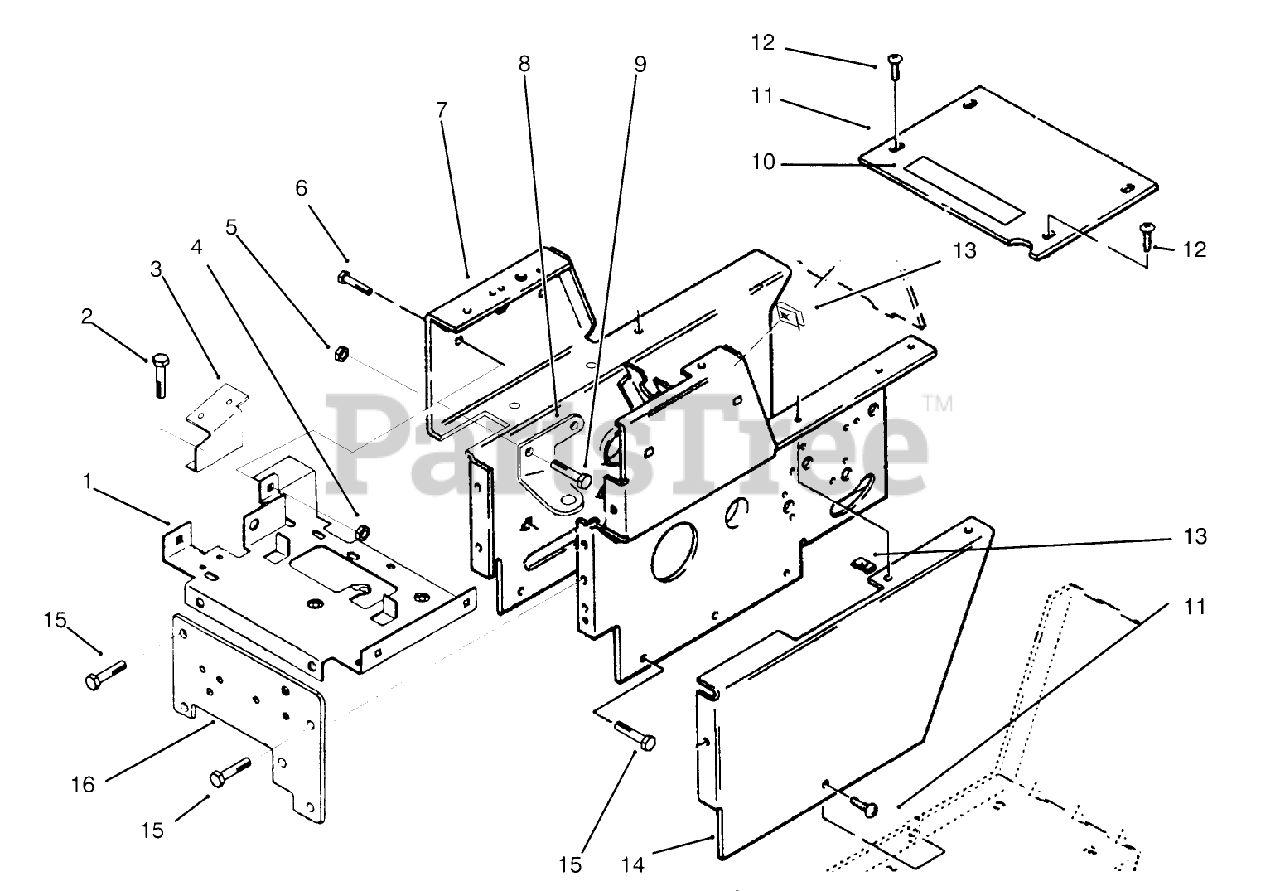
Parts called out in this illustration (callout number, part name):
2	Bolt
5	NUT-LOCK, NI
9	SCREW-HH
11	COVER PLATE/DECAL ASM
15	SCREW
